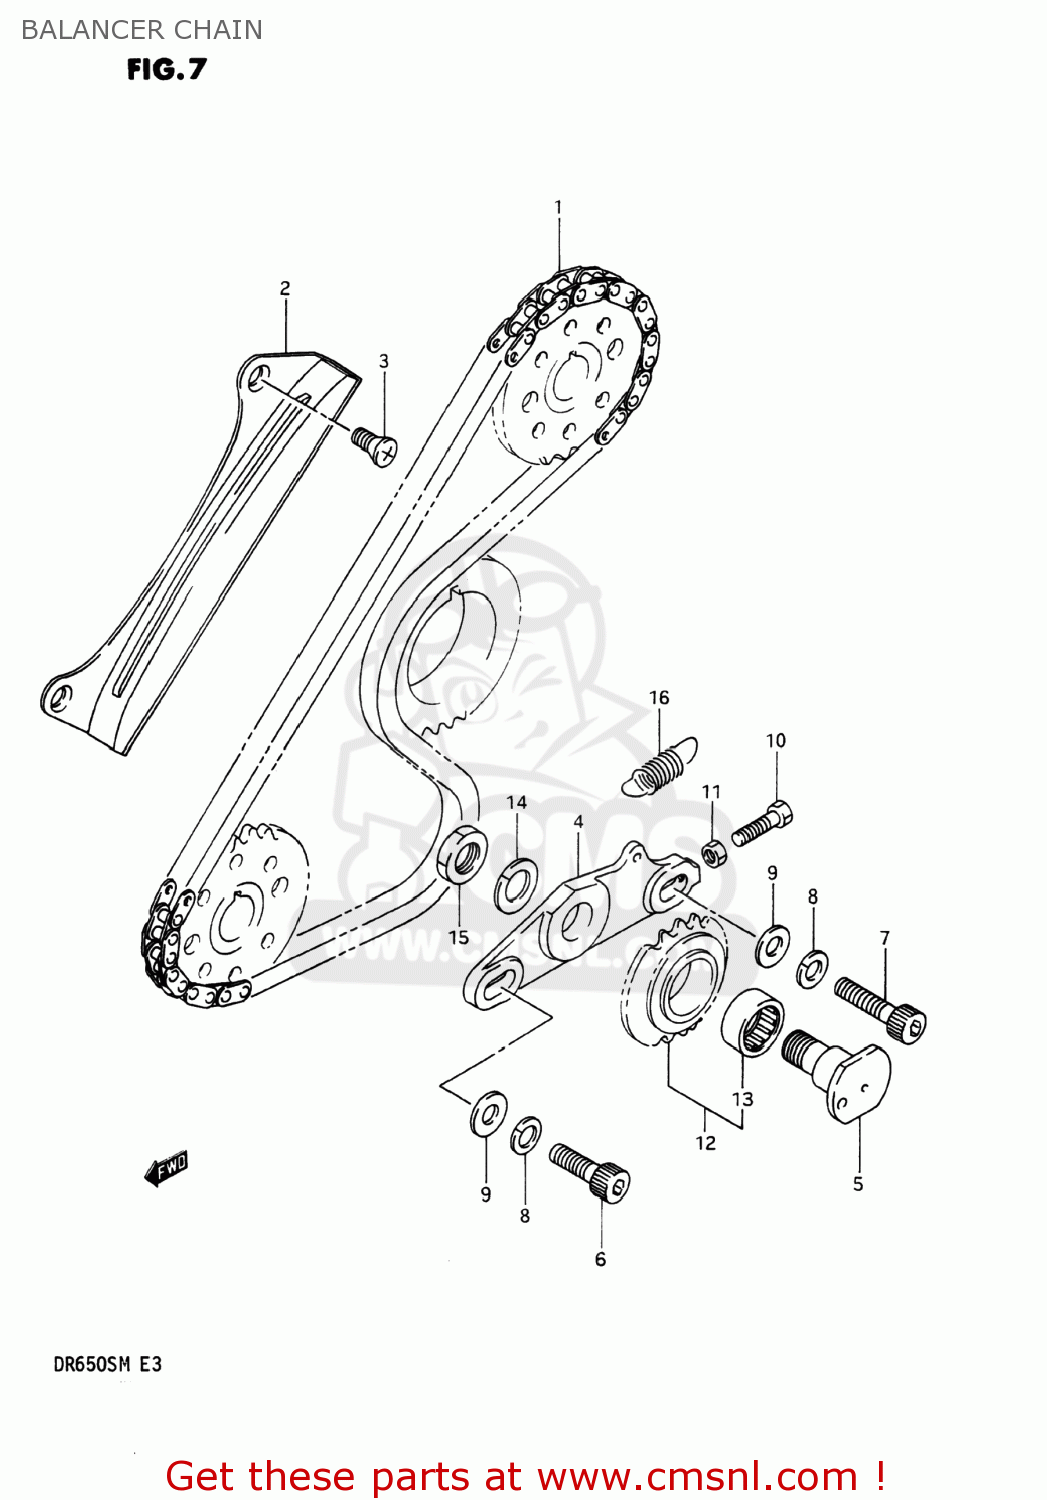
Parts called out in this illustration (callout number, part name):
1	GOVERNOR ASSEMBLY,EXHAUST
2	GUIDE,BALANCER CHAIN
3	SCREW M6X1X16
4	BRACKET,BALANCER CHAIN
5	SHAFT,BALANCER CHAIN TENSIONER
6	BOLT(8X22)
7	BOLT, REAR (8X30)
8	LOCK WASHER
9	WASHER
10	BOLT 5X20
11	NUT
12	SPRKT,BALANCER CHAIN TENSIONER
13	BEARING(17X23X12)
14	WASHER,LOCK 12
15	NUT
16	SPRING
